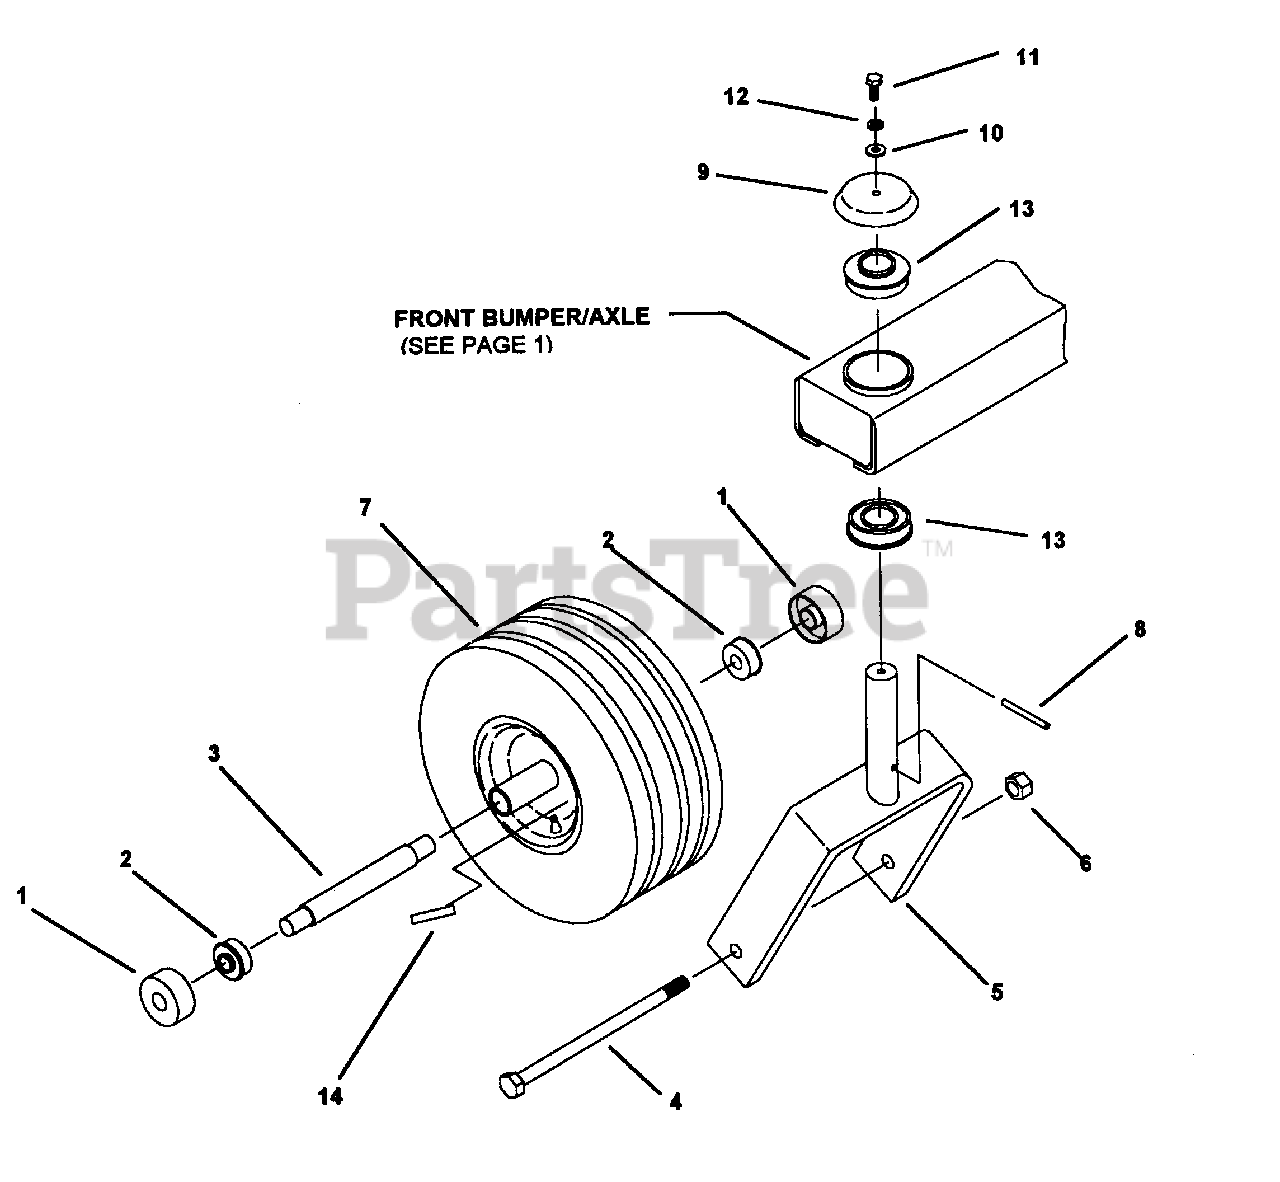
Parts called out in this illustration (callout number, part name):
1	SHIELD, BEARING
2	BEARING, 5/8 I.D. X 1-3/8 O.D.
3	SPACER, BEARING
4	BOLT, 1/2-13 X 8" GR.5
5	CASTER WELDMENT
6	NUT, 1/2-13, STOVER
8	PIN, SPIRAL, 3/16 X 2 HEAVY DUTY
9	CAP, BEARING
10	WASHER, FLAT STD. 1/4"
11	BOLT, 1/4-20 X 3/4" GR.5 W/NYLON PATCH
12	LOCK WASHER, 1/4" HEAVY SPRING
13	BEARING, SPD SF-1B-32 W/0 COLLAR
14	DECAL, TIRE PRESSURE
